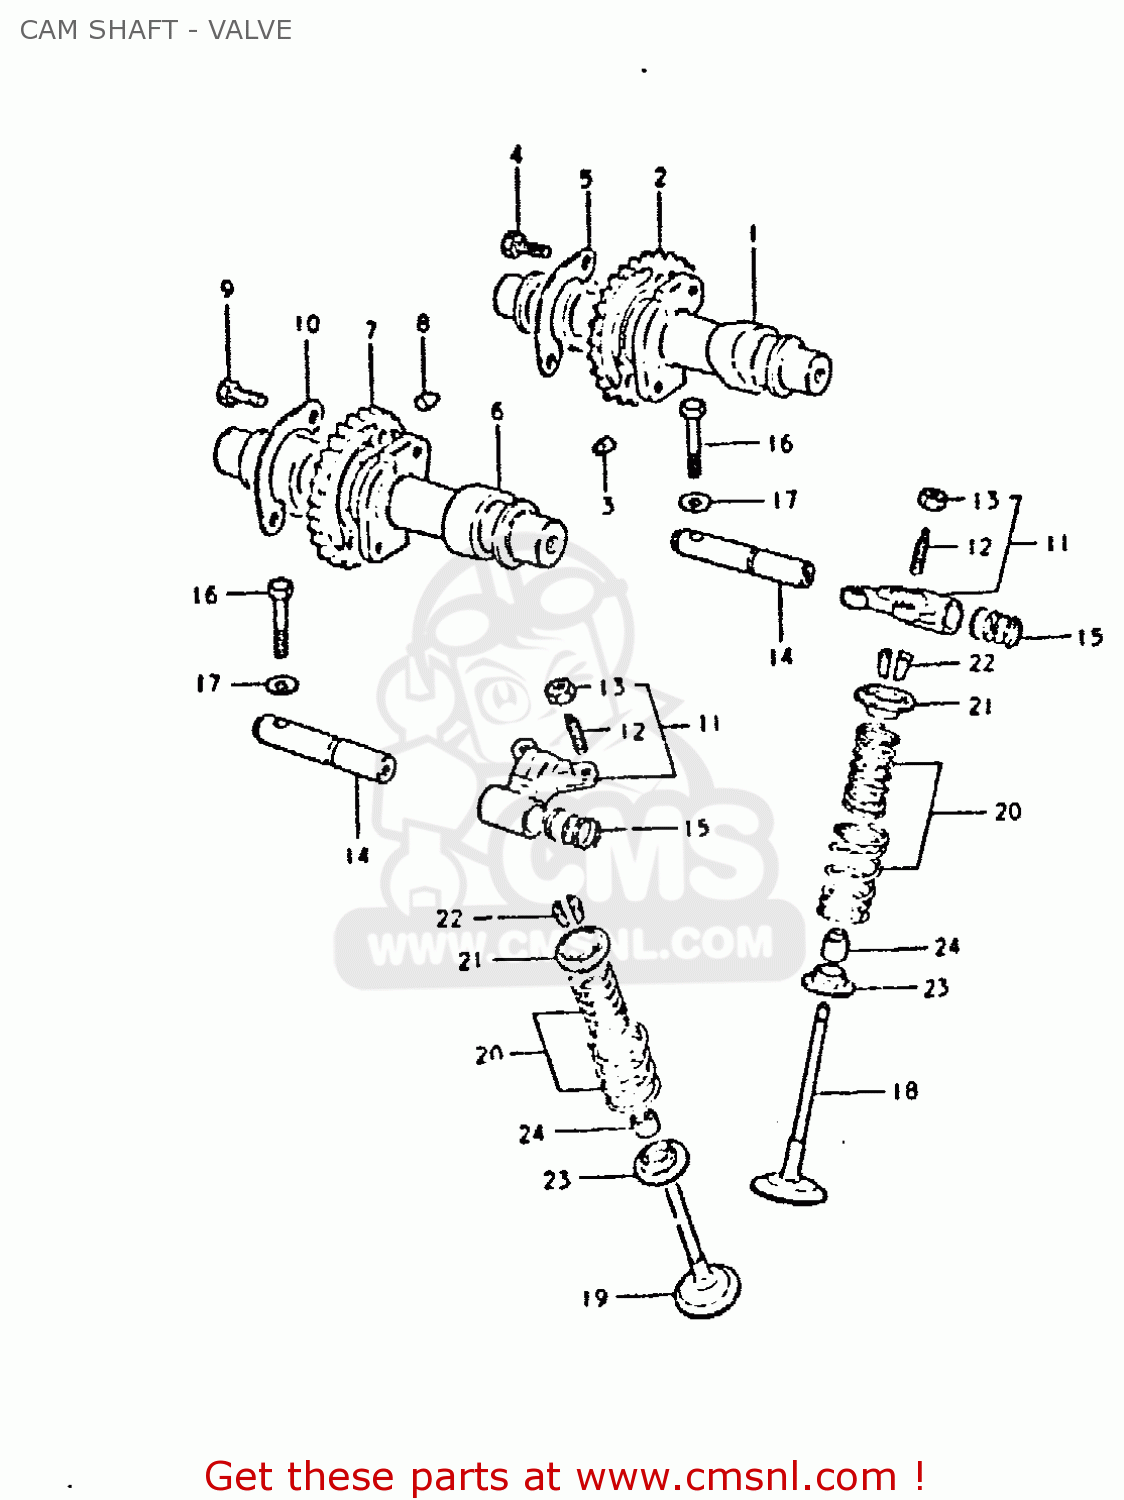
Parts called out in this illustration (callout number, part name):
1	CAM SHAFT, INTAKE
2	SPROCKET (NT:30)
3	PIN,SPROCKET
4	BOLT(6X12.5)
5	WASHER,CAM CHAIN SPROCKET
6	CAMSHAFT,EXHAUST
7	SPROCKET (NT:30)
8	PIN,SPROCKET
9	BOLT(6X12.5)
10	WASHER,CAM CHAIN SPROCKET
11	ARM,VALVE ROCKER
12	SCREW,TAPPET ADJUSTING
13	NUT,ADJUSTING
14	SHAFT,VALVE ROCKER ARM
15	SPRING
16	BOLT
17	WASHER
18	VALVE,INTAKE
19	VALVE,EXHAUST
20	SHIM,TAPPET
21	RETAINER,VALVE SPRING
22	COTTER VALVE
23	SEAT,VALVE SPRING
24	OIL SEAL
